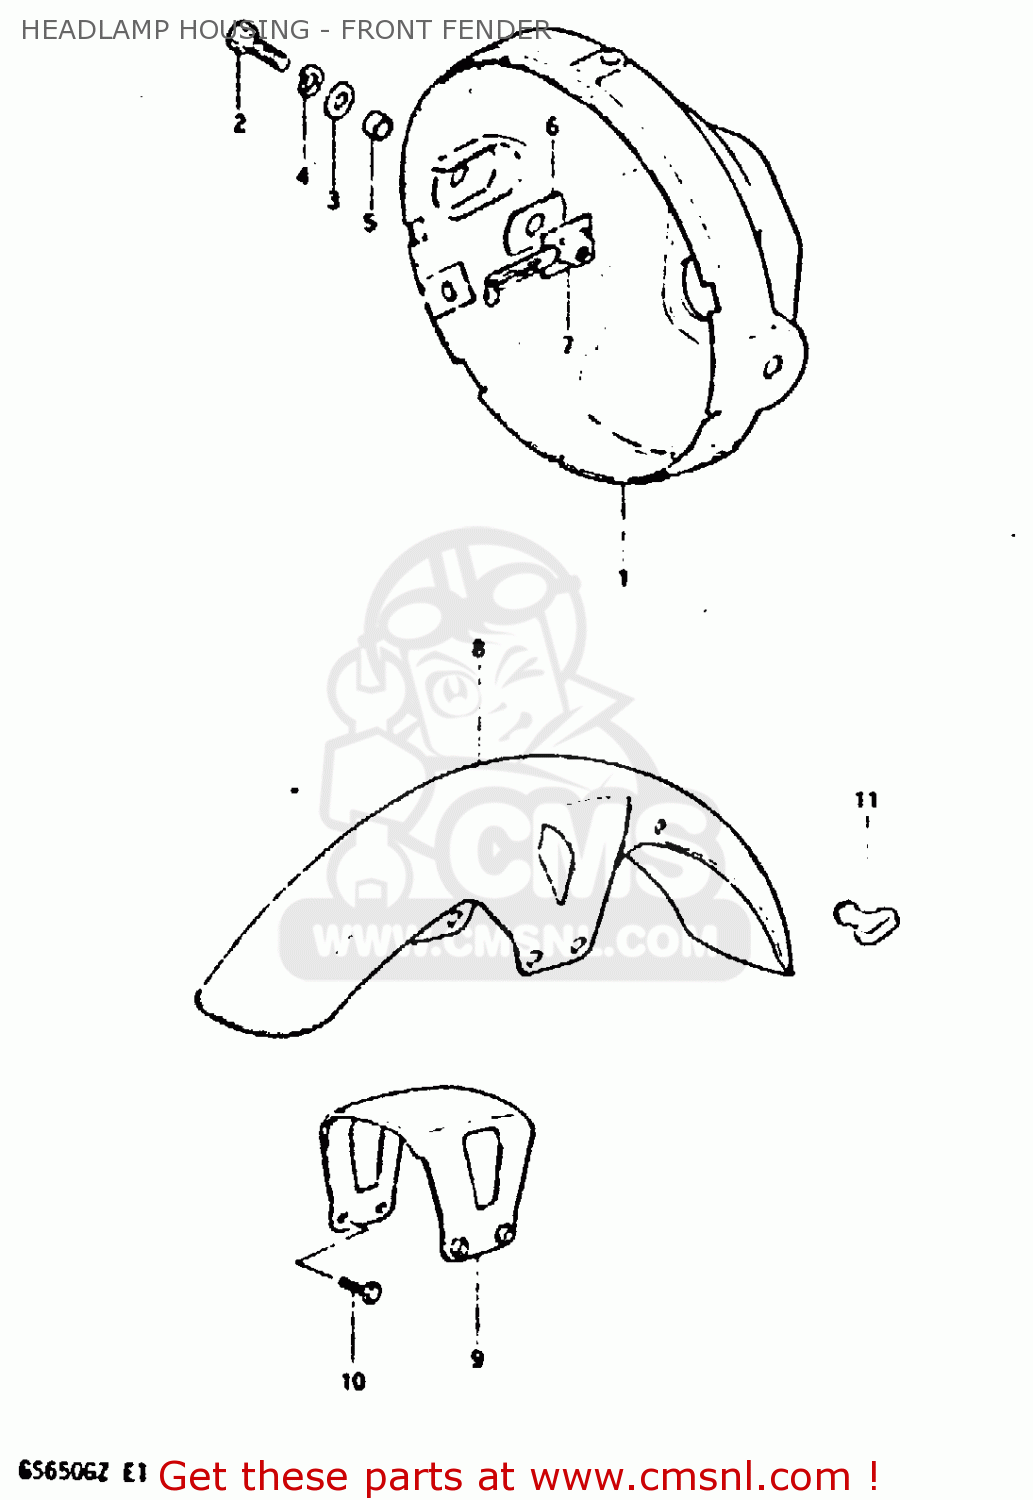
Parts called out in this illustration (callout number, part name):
1	HOUSING,HEADLAMP
2	BOLT
3	WASHER
4	LOCK WASHER
5	SPACER (8.8X12X7)
6	CUSHION
7	PLATE,HEADLAMP HOUSING
8	FENDER,FRONT
9	BRACE,FRONT FENDER
10	BOLT 8X16
11	GUIDE,CABLE
